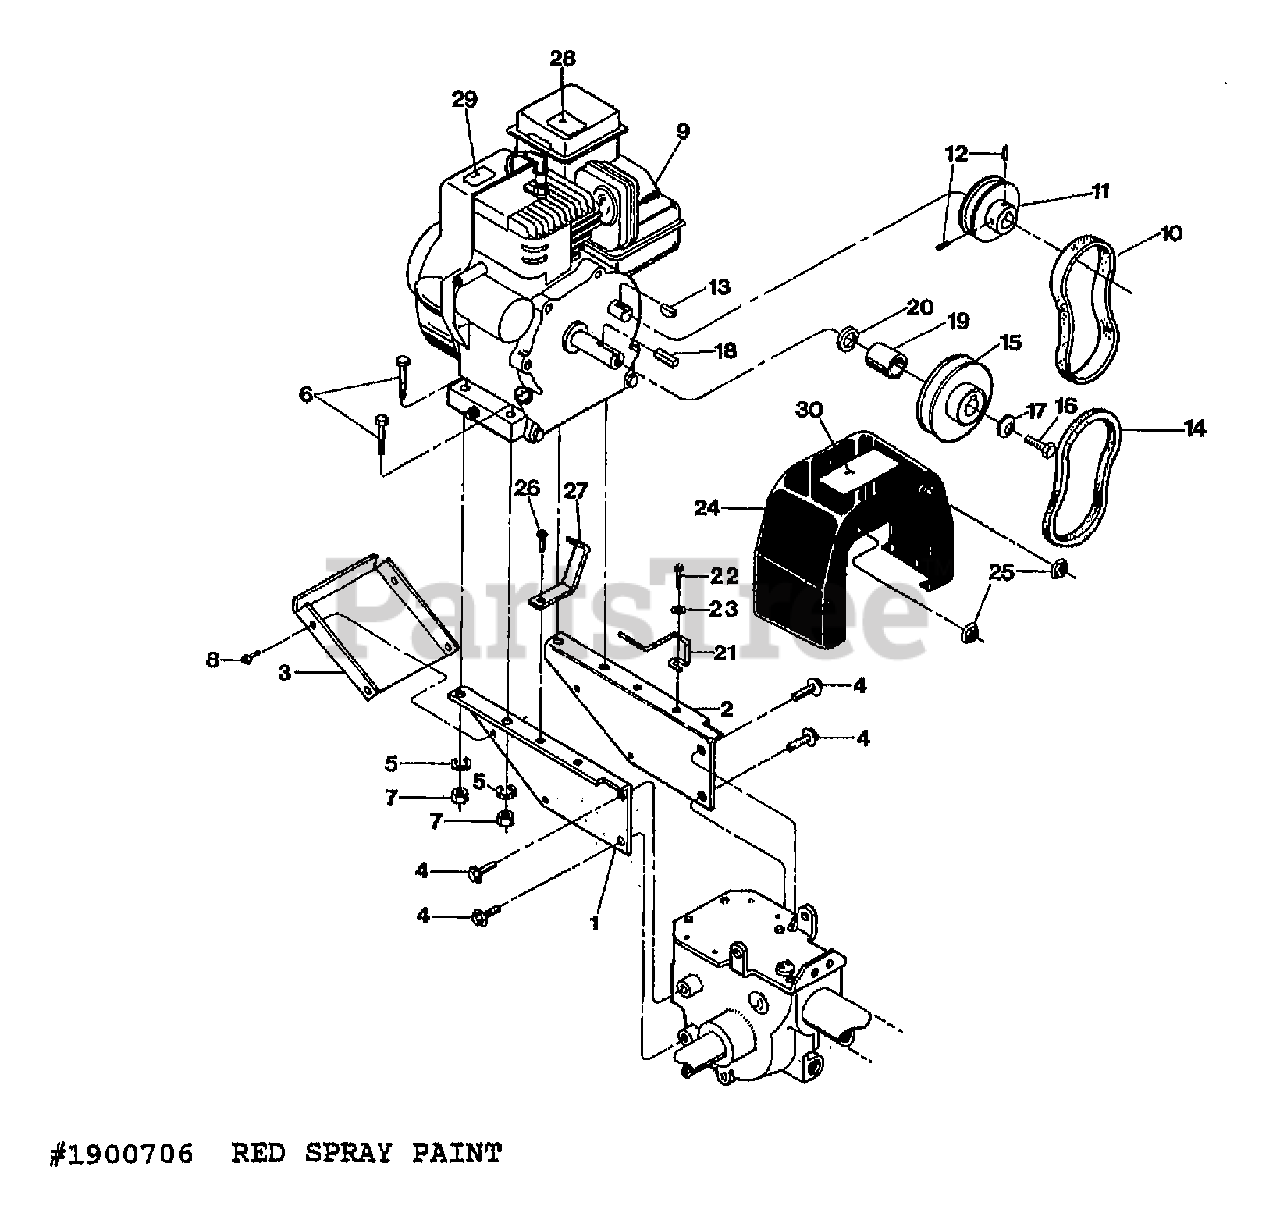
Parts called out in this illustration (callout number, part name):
1	BRKT-ENG LT P4
2	BRKT-ENG RT PNT
3	PAN-ENG BRKT PNT
4	SCR-HFLK 5/16-18X.75 ZP
5	WASHER-LK .312 ZP
6	SCR-HH 5/16-18X1.5 G5 ZP
7	NUT-HEX 5/16-18 ZP
8	SCR-HH SEMS 10-32 X .5 ZP
9	ENGINE, BRIGGS & STRATTON 5HP,
10	BELT-FLAT (SEE BELT SET BELOW)
11	PULLEY-REV DRILL/TAP
12	SCR-SS 1/4-20 X .25 (SECURES REVERSE ENGINE PULLEY)
13	KEY-WOODRUFF #5
14	BELT-V GROOVE FWD SMFRAME (SEE BELT SET BELOW)
15	PULLEY-ENGINE MACH
16	SCR-HH 5/16-24X.75 G5 ZP
17	WASHER-.827X.331X.098
18	KEY-.188 SQX1.0
19	SPACER-.938X.755X1.19
20	SHIM-1.0X.7656X.031
21	GUIDE-BELT FWD
22	SCR-HWH 1/4-20 X .75 STH
23	WASHER-FLAT 1/4 SAE
24	COVER-BELT W/DECAL (INCL. 30)
25	NUT-HFLK 5/16-18 ZP
26	SCR-HWH 1/4-20 X .5 STH
27	GUIDE-BELT REV PNT
28	DECAL - HOT SURFACE
29	DECAL-STABIL STARTING
30	DECAL-BELT COVER OPC
